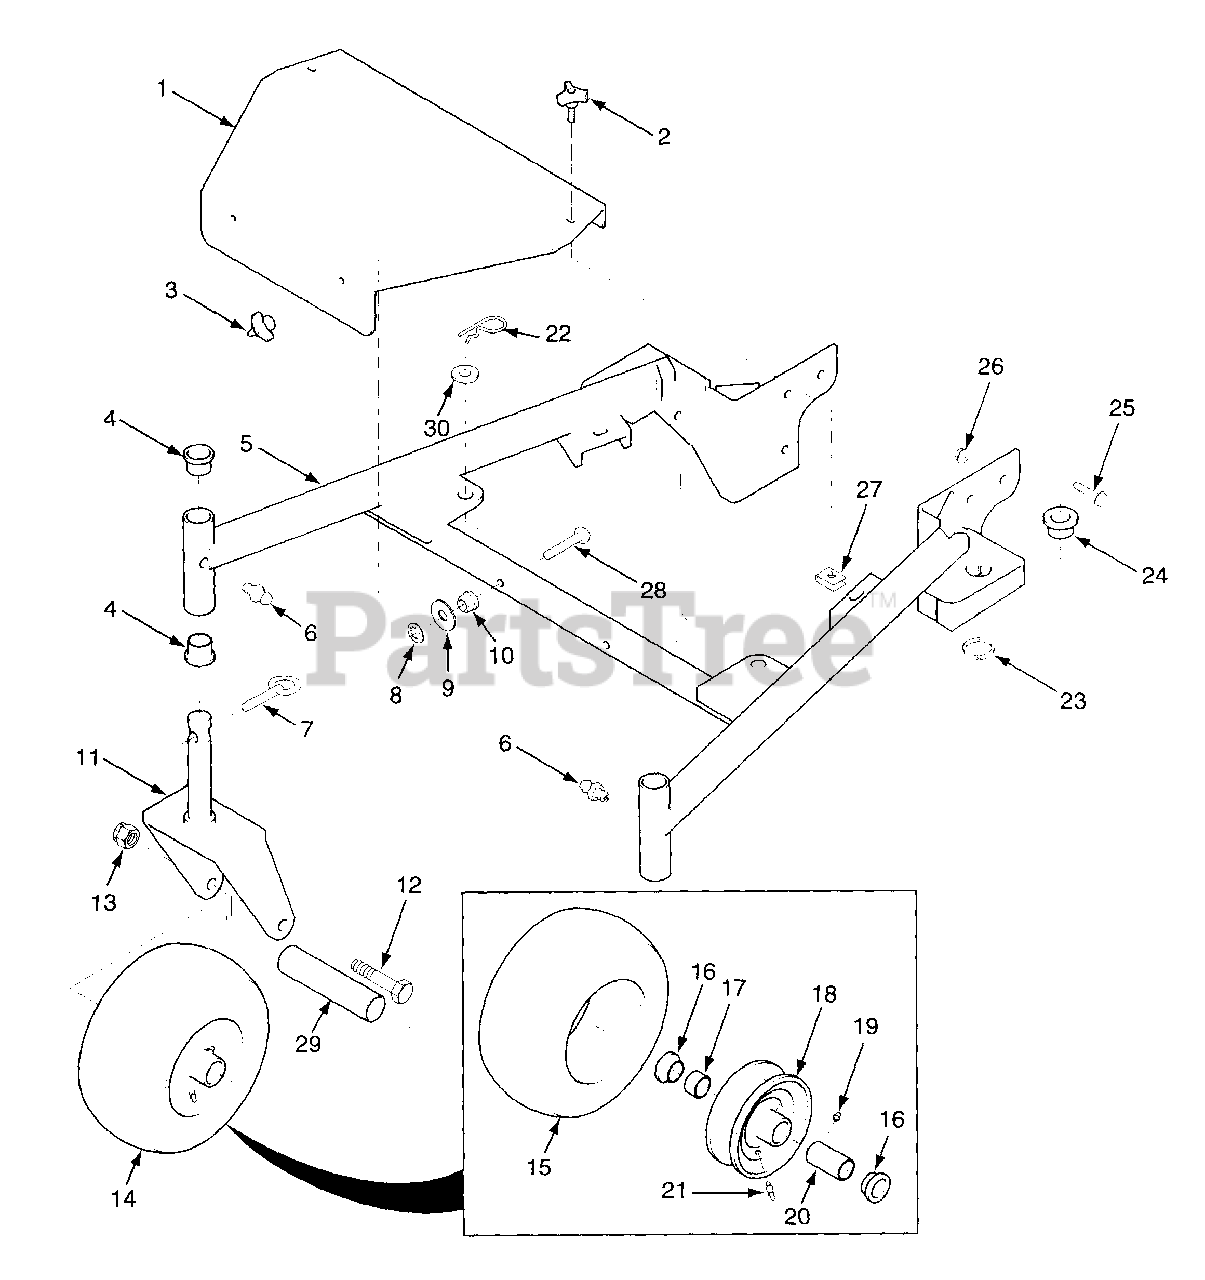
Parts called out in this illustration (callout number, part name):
1	Belt Cover With Decal
2	Knob With Stud
3	Knob, Deck Cover Mounting
4	Bushing, Caster
5	Frame Weldment, Deck Mounting - 52"
6	Grease Fitting Str. 1/4-28 Self Tap
7	Quick Pin, .438 Dia
8	Nut, Push-On - 3/8 Thd.
9	Flatwasher, 3/8 (.391 x .938 x .105)
10	Nut, 3/8-16 Serrated Flange Hex Head
11	Yoke, Caster Wheel
12	Capscrew, Hex Head 1/2-13 x 6.50"
13	Locknut, 1/2-13 Elastic Stop
14	Wheel Assembly, Caster
15	Tire, 11 x 4.00-5
16	Retainer
17	Roller Bearing
18	Rim, 5.0 x 2.75 With Zerk & Valve
19	Grease Fitting Str. 1/4-28
20	Roller Bearing .625 x 3.25"
21	Tire Valve, Purchase Locally
22	Hair Pin Cotter, .177 x 3.25"
23	Retaining Ring 1.50 Ext.
24	Bushing, Deck Adjustment Pin
25	Capscrew, Hex Head 7/16-14 x 1.0"
26	Nut, 7/16-14 Serrated Flange Hex
27	U-Nut, 3/8-16
28	Capscrew, Hex Head 3/8-16 x 2.25"
29	Sleeve, Caster Wheel
30	Flatwasher, 5/8 - (.688 x 1.75 x .134)
